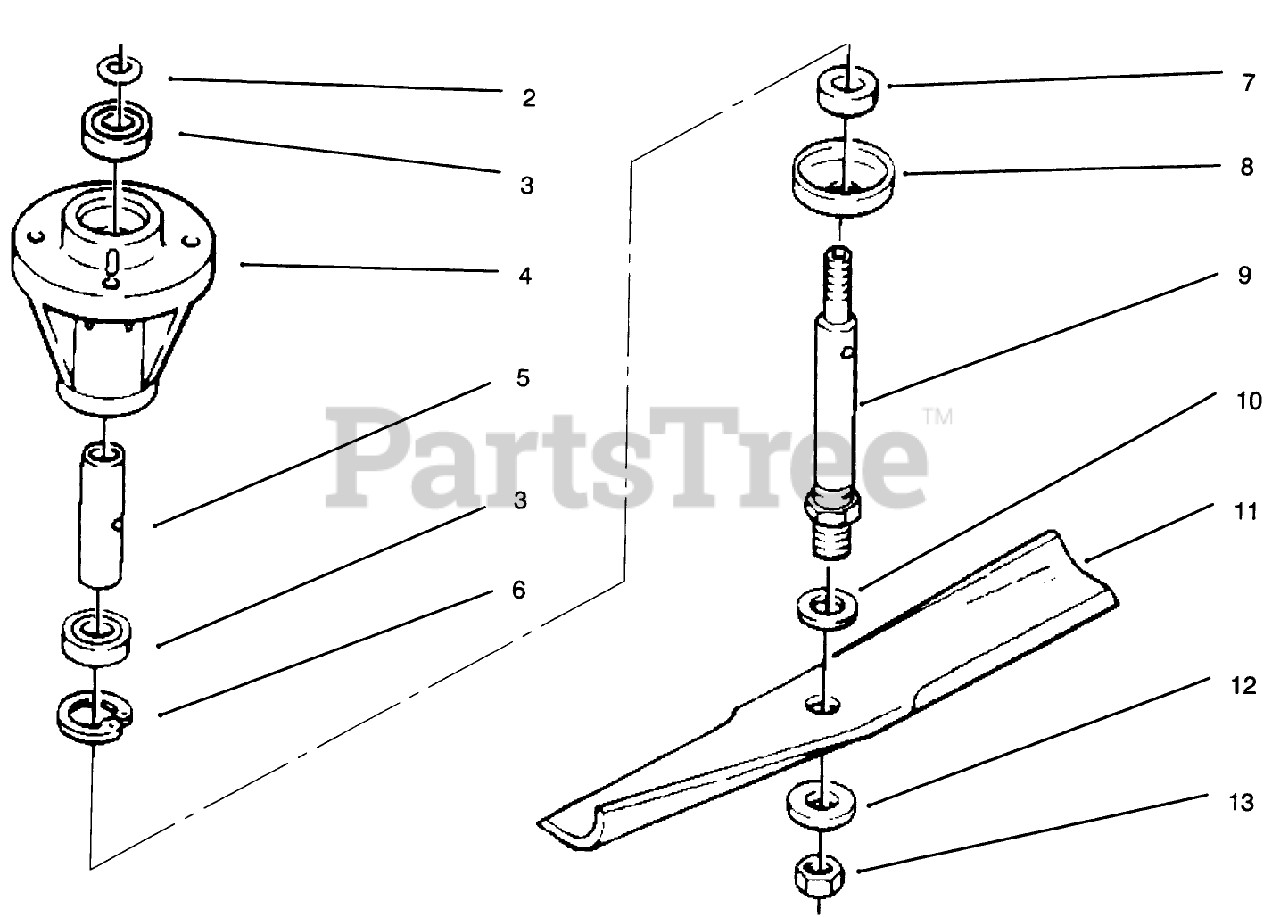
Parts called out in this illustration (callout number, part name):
2	O RING
3	BEARING-BALL
4	HOUSING-SPINDLE
6	RING-RETAINING
7	SPACER-BLADE
8	CUP-SPINDLE
9	SHAFT-SPINDLE
10	WASHER-FLAT
11	BLADE KIT (3- 79-2920)
12	WASHER-FLAT
13	NUT-JAM
